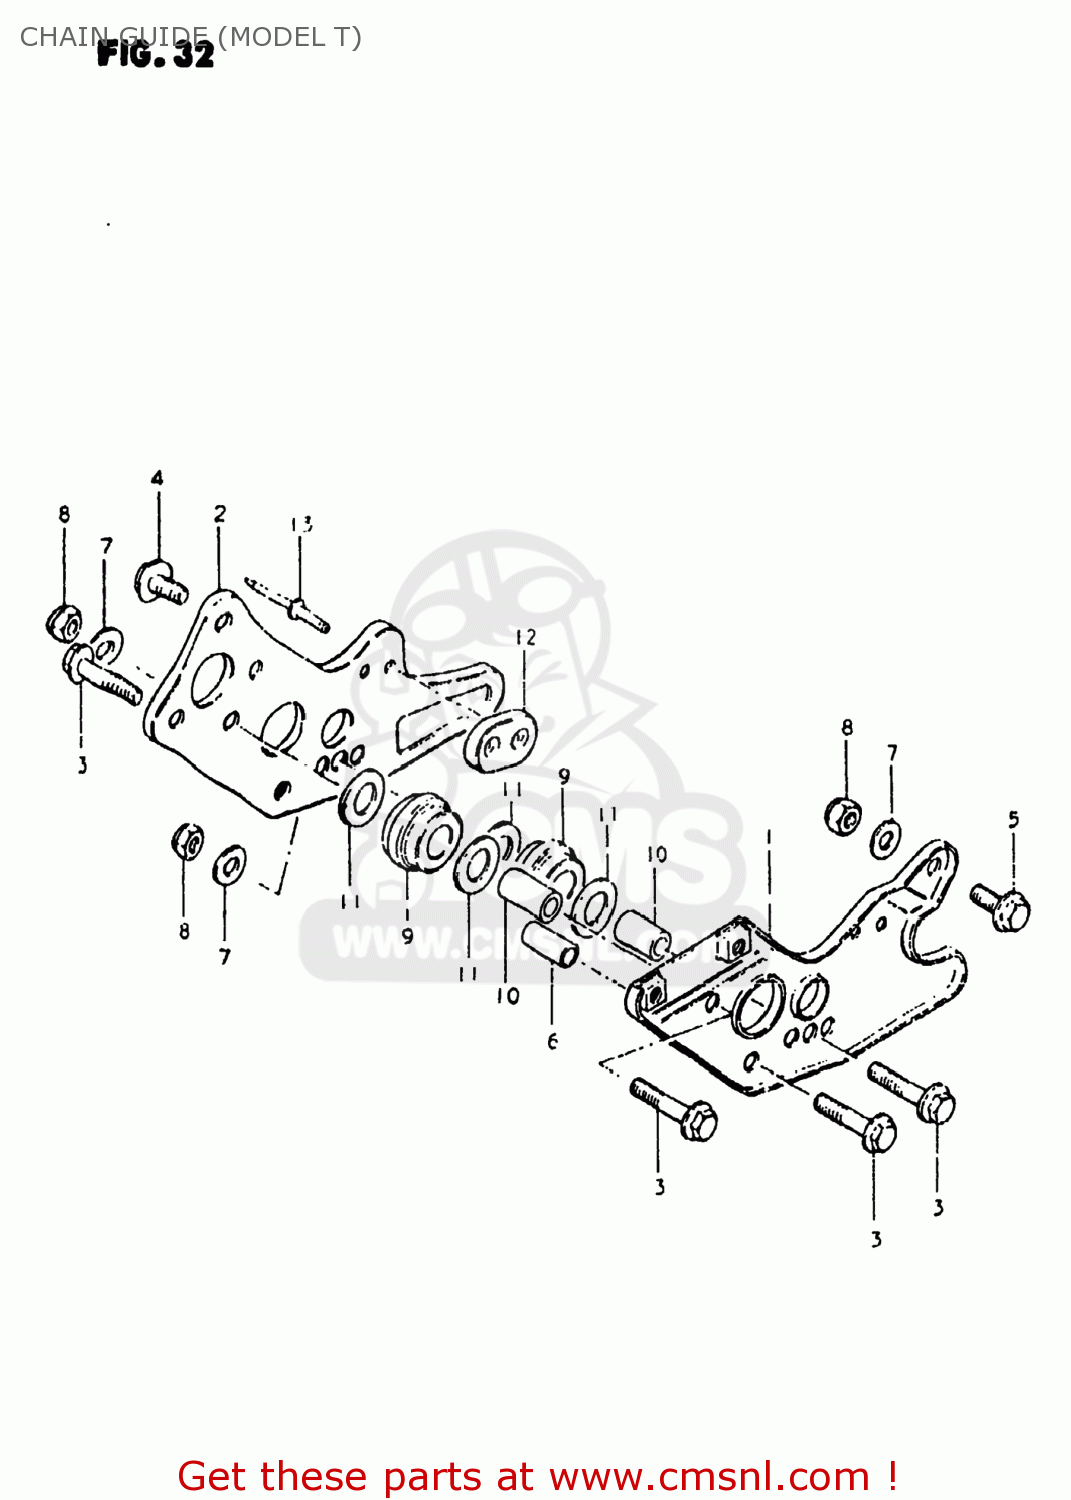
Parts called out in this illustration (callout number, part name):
1	PLATE,CHAIN GUIDE,OUTER
2	PLATE,CHAIN GUIDE,INNER
3	BOLT 6X35
4	BOLT
5	BOLT
6	SPACER(6.8X10X24.2)
7	WASHER
8	NUT 6MM
9	ROLLER,CHAIN GUIDE
10	SPACER,CHAIN GUIDE ROLLER
11	WASHER
12	PAD,DRIVE CHAIN GUIDE
13	RIVET
